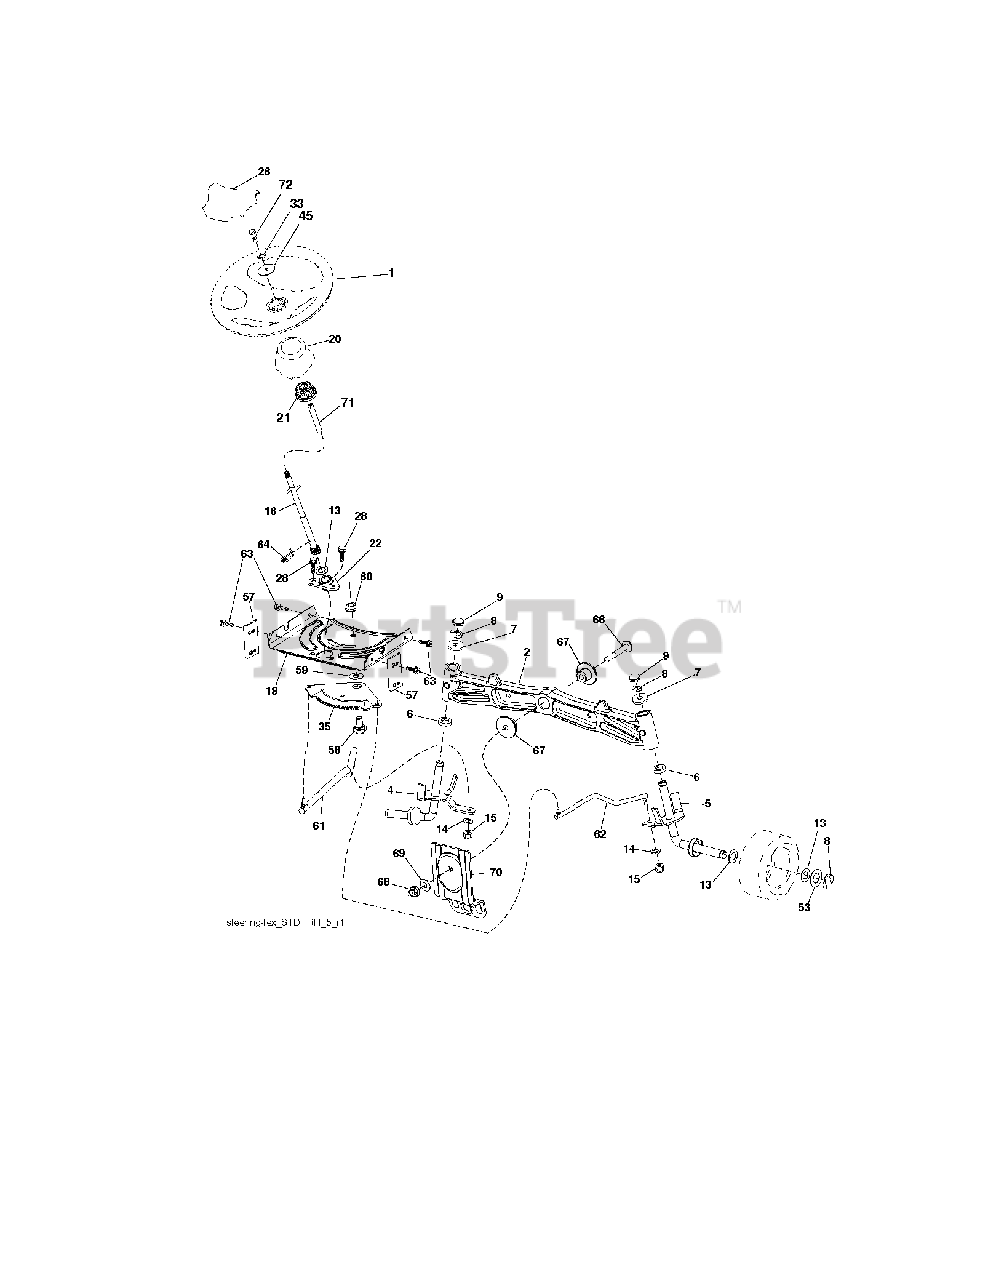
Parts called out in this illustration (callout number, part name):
1	WHEEL.STEERING.MLT.BR.YEL/OVRM
2	AXLE.CAST.IRON
4	SPINDLE.WELDED.LH.15"TEX
5	SPINDLE.WELDED.RH.15"T
8	RING CLIP
9	CAP.SPINDLE.BLACK
14	WASHER, LOCK 3/8
15	NUT CROWNLOCK 3/8-24
16	SHAFT.STEER.3/4.NON-PLATED.TEX
19	PLATE.STEER.DDL.NLT/NG
20	BOOT STEERING BLACK
21	ADAPTER, WHEEL STNG..
22	STEERING.SUPT.LOWER.
26	CAP.WHL.STRNG.MULTI.BRND.YEL
28	SCREW, 3/8-16X3/4
33	LOCKWASHER
35	GEAR.SECTOR.PLATE.DDL.
45	WASHER.11/32
53	WASHER.HARDENED
57	BRACKET.UPSTOP.TEX
58	BOLT.SHOULDER.SECTOR.P
59	WASHER.THURST.SECTOR.S
60	NUT FLANGE LOCK 5/8-11
61	DRAGLINK.LH.BALLSTUD.D
62	DRAGLINK.RH.BALLSTUD.D
63	SCREW
64	RETAINER.CLIP.SPRING.S
66	BOLT HEX FGHD 7/16-14 X 3 SERR
67	BUSHING.PM.FRONT AXLE
68	NUT.LOCK.FLANGE.7/16
69	WASHER.1.5X.505X.118
70	BRKT.DECK.SUSPENSION.F
71	SHAFT.EXTEN.STRG.SPLINE
72	BOLT 5/16-18 X 4 W/PATCH
